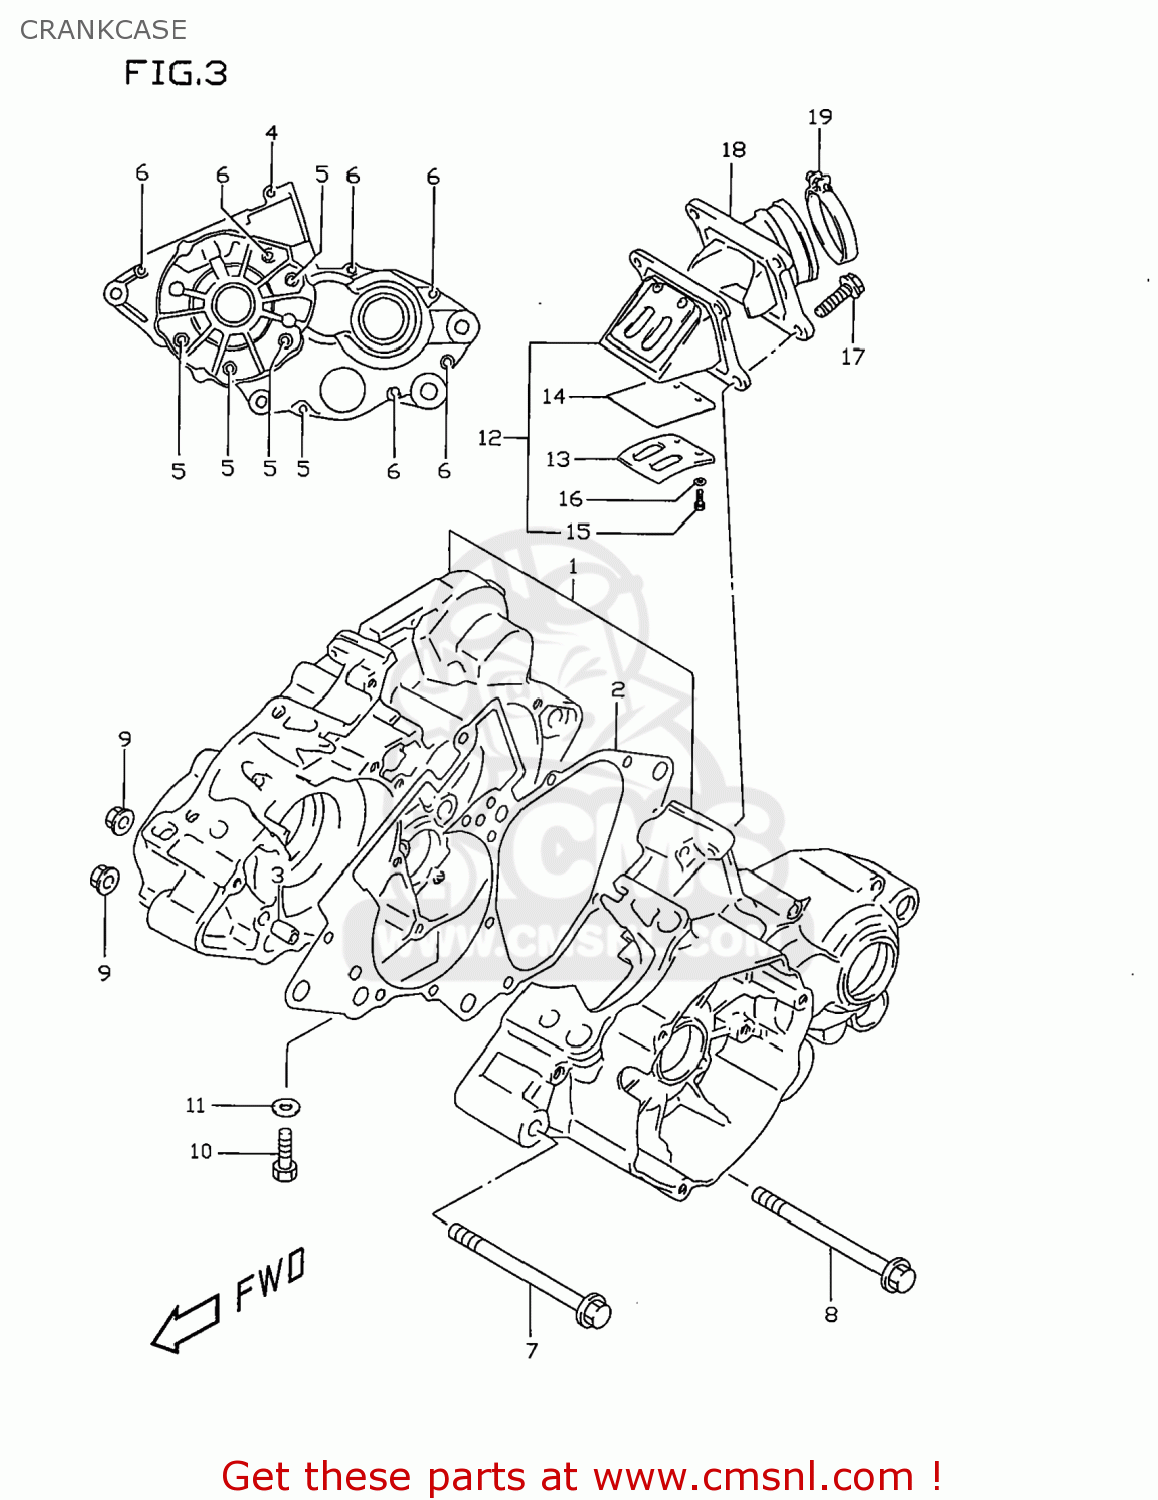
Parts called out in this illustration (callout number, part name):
1	CRANKCASE SET
2	GASKET,CRANKCASE (NAS)
3	PIN
4	BOLT
5	BOLT
6	BOLT
7	BOLT 8X92
8	BOLT(8X102)
9	NUT
10	BOLT
11	GASKET(8.2X14X1) (NAS)
12	VALVE ASSY,REED
13	STOPPER,REED VALVE
14	VALVE,REED
15	SCREW
16	WASHER,LOCK
17	SCREW
18	PIPE,INTAKE
19	CLAMP
